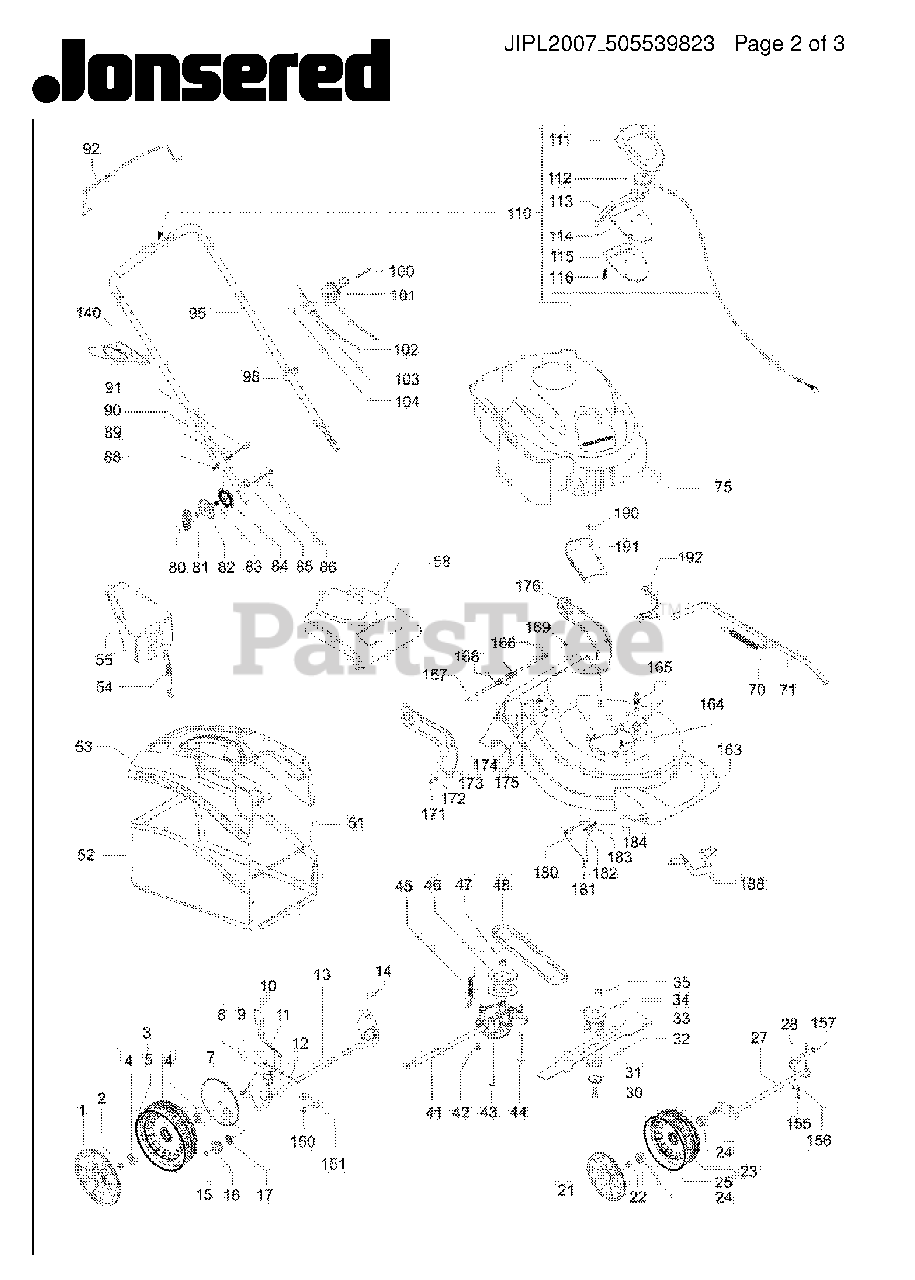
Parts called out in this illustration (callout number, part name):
111	CASE.TOP.GRAY
112	PULLEY, DRIVE CONTROL
113	LEVER
114	CASE BOTTOM
115	BRACKET, DRIVE CONTROL
116	SCREW, PHILLIPS HEAD 10 X 5/8
